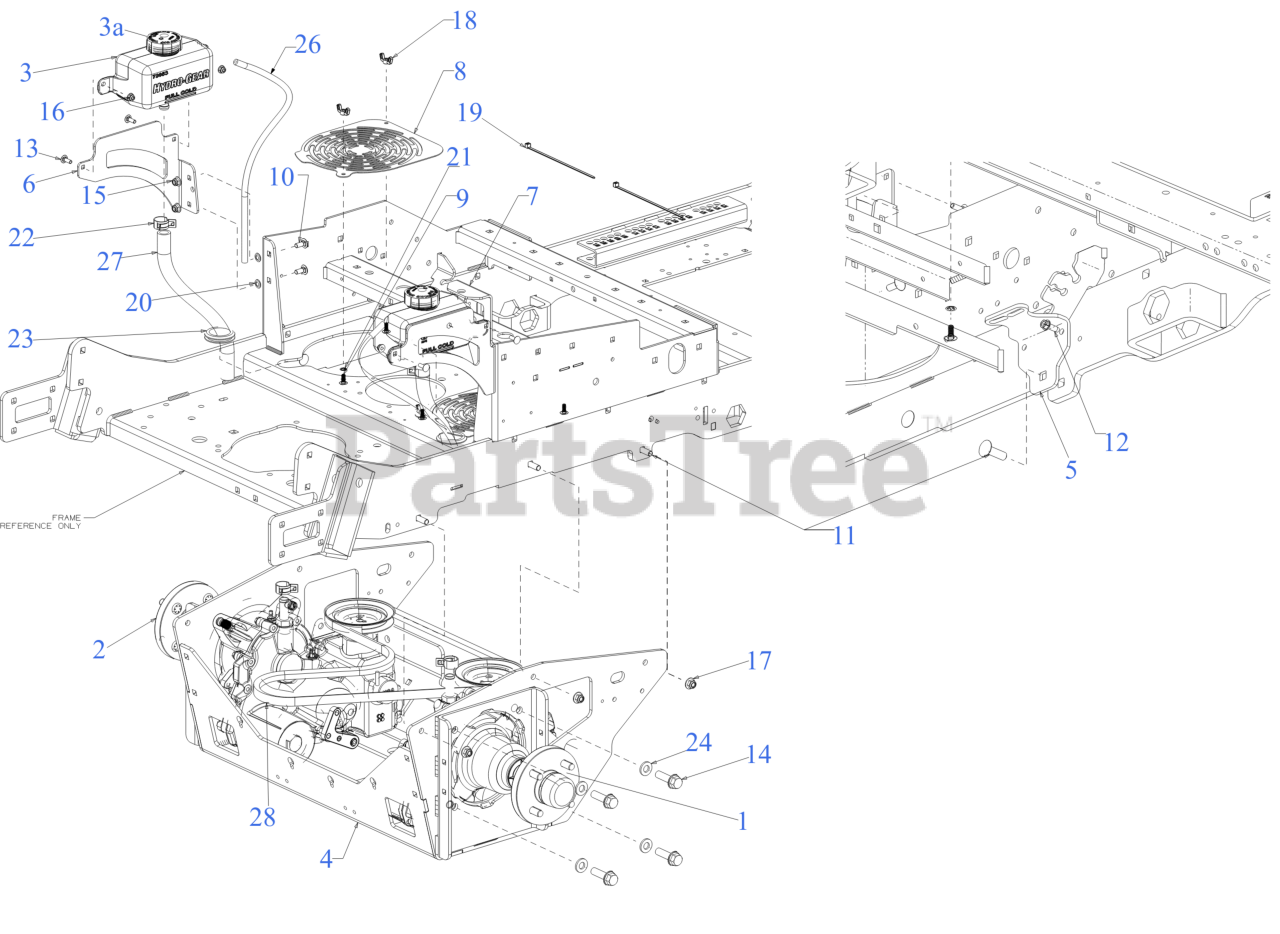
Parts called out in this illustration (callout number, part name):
1	TRANSMISSION (RH)
2	TRANSMISSION (LH)
3	1L EXPANSION TANK
4	SUB FRAME BRACKET
5	LAPBAR DAMPER MOUNT BRACKET
6	TANK MOUNT BRACKET (LH)
7	TANK MOUNT BRAKET (RH)
8	TRANSMISSION COVER PLATE
9	CARRIAGE BOLT 1/4-20 x .62
10	CARRIAGE BOLT 5/16-18 x .75
11	CARRIAGE BOLT 3/8-16 X1.25 GR5
12	SCREW 1/4-20 x .750
13	SCREW 1/4-20 x .75 GR5
14	FLANGE BOLT 1/2-13:1.75:GR5
15	FLANGE LOCK NUT 5/16-18
16	FLANGE LOCK NUT
18	WING NUT 1/4-20
19	7" CABLE TIE
21	RETAINER-BOLT .25ID x .50OD
22	HOSE CLAMP
23	RUBBER GROMMET (1.50X2.13X.563)
24	FLAT WASHER .510 x 1.000 x .125
26	VENT HOSE 3/16 ID 45"LG
27	OIL HOSE 5/8 ID X 13.5 LG
28	V-BELT 65.58"
